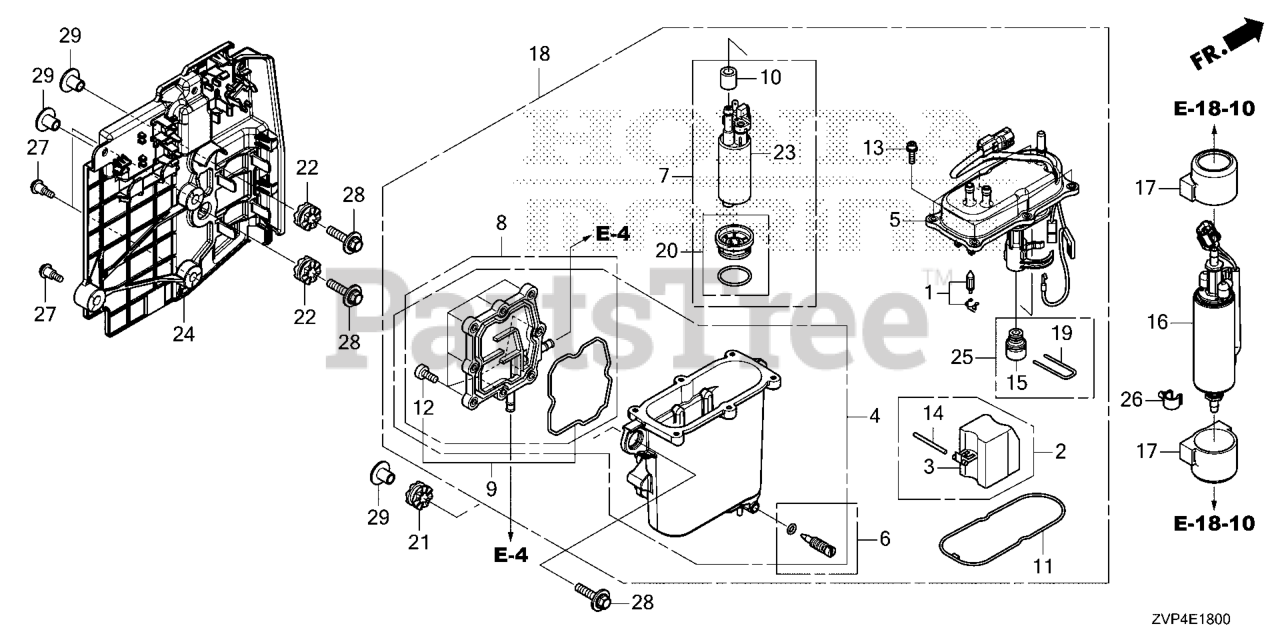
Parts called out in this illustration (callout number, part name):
1	VALVE SET, INLET
3	FLOAT ASSY.
5	COVER SET, TOP
6	SECREW SET
7	PUMP SET, FUEL
8	CVR, WATER COOLER
9	SEAL SET, COVER
11	SEAL, COVER
12	SCREW (M5X16)
13	SCREW (M5X16)
14	PIN, FLOAT
15	REGULATOR ASSY.
16	PUMP ASSY., FUEL
17	RUBBER, FUEL PUMP
18	VAPOR SEPARATOR
19	CLIP, REG RETAINING
20	ADAPTER SET
21	GROMMET, VAPOR SEPARATOR
22	GROMMET, VAPOR SEPARATOR
23	PUMP ASSY., FUEL
25	REGULATOR SET
26	CLAMP B, FUEL TUBE
27	BOLT, T/B COVER
28	BOLT-WASHER (8X35)
29	COLLAR (8.5X14.5)
